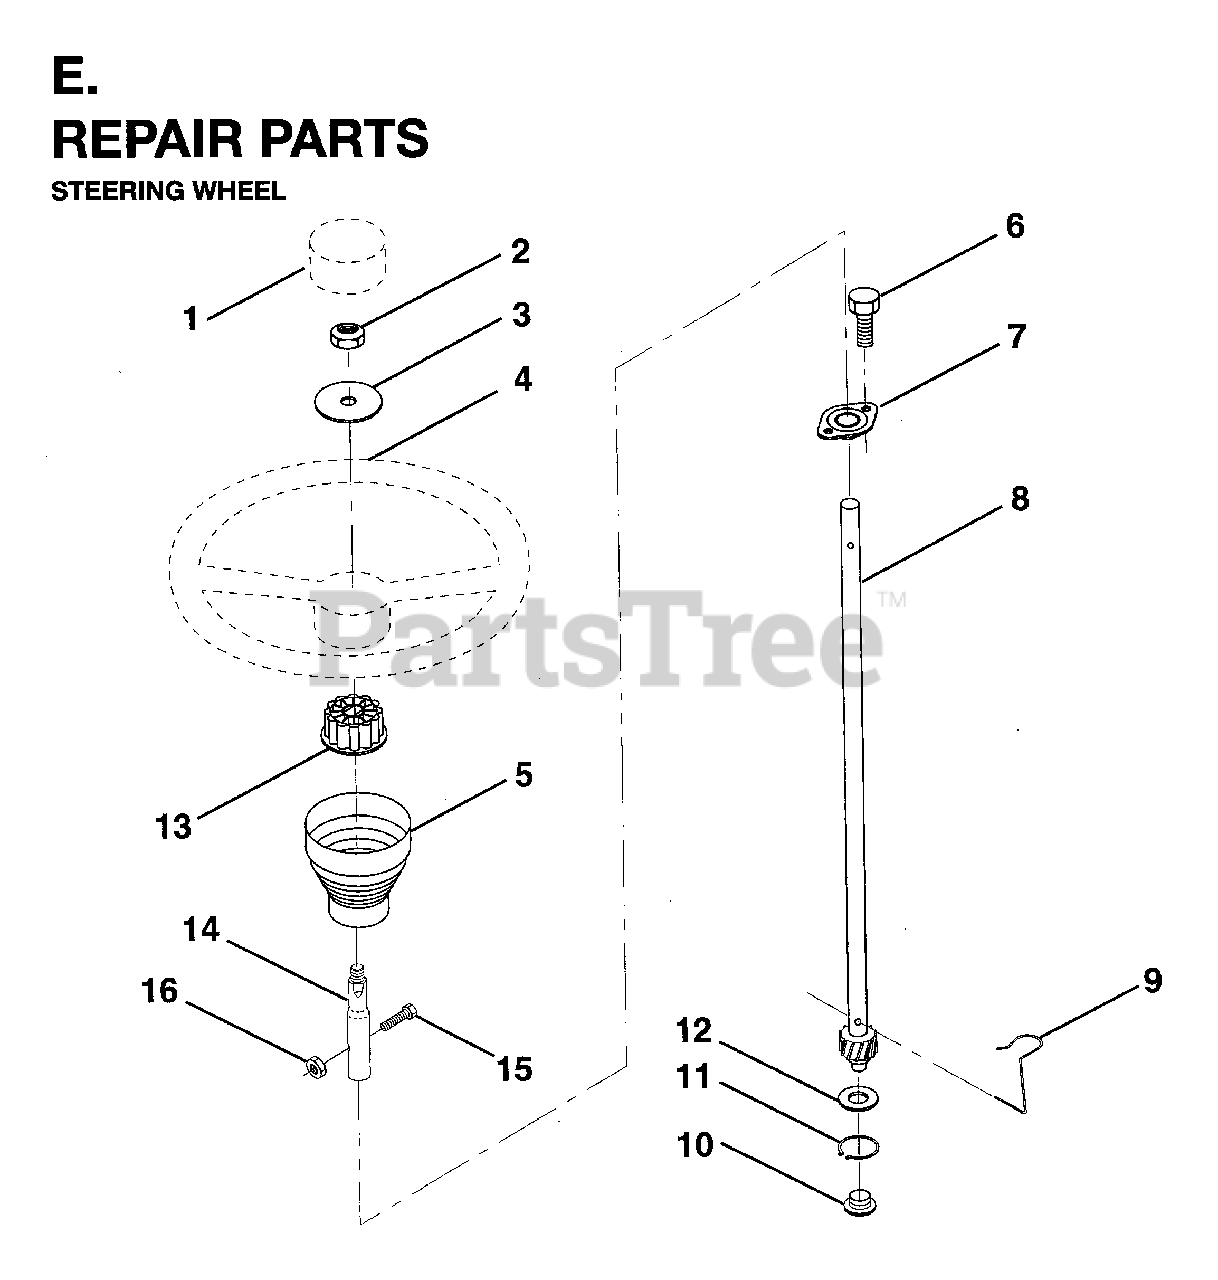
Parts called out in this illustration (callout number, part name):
2	NUT
3	WASHER T
7	BUSHING-STRG LT
8	STEERING SHAFT
9	STEERING CLIP
10	BUSHING STEER LWR
13	ADAPTER-WHEEL LT
14	SHAFT EXTENSION
15	BOLT.5/16-18X1-1/4 FULL.THREAD
16	NUT.71038.31-18.HEX.NYLOCK
